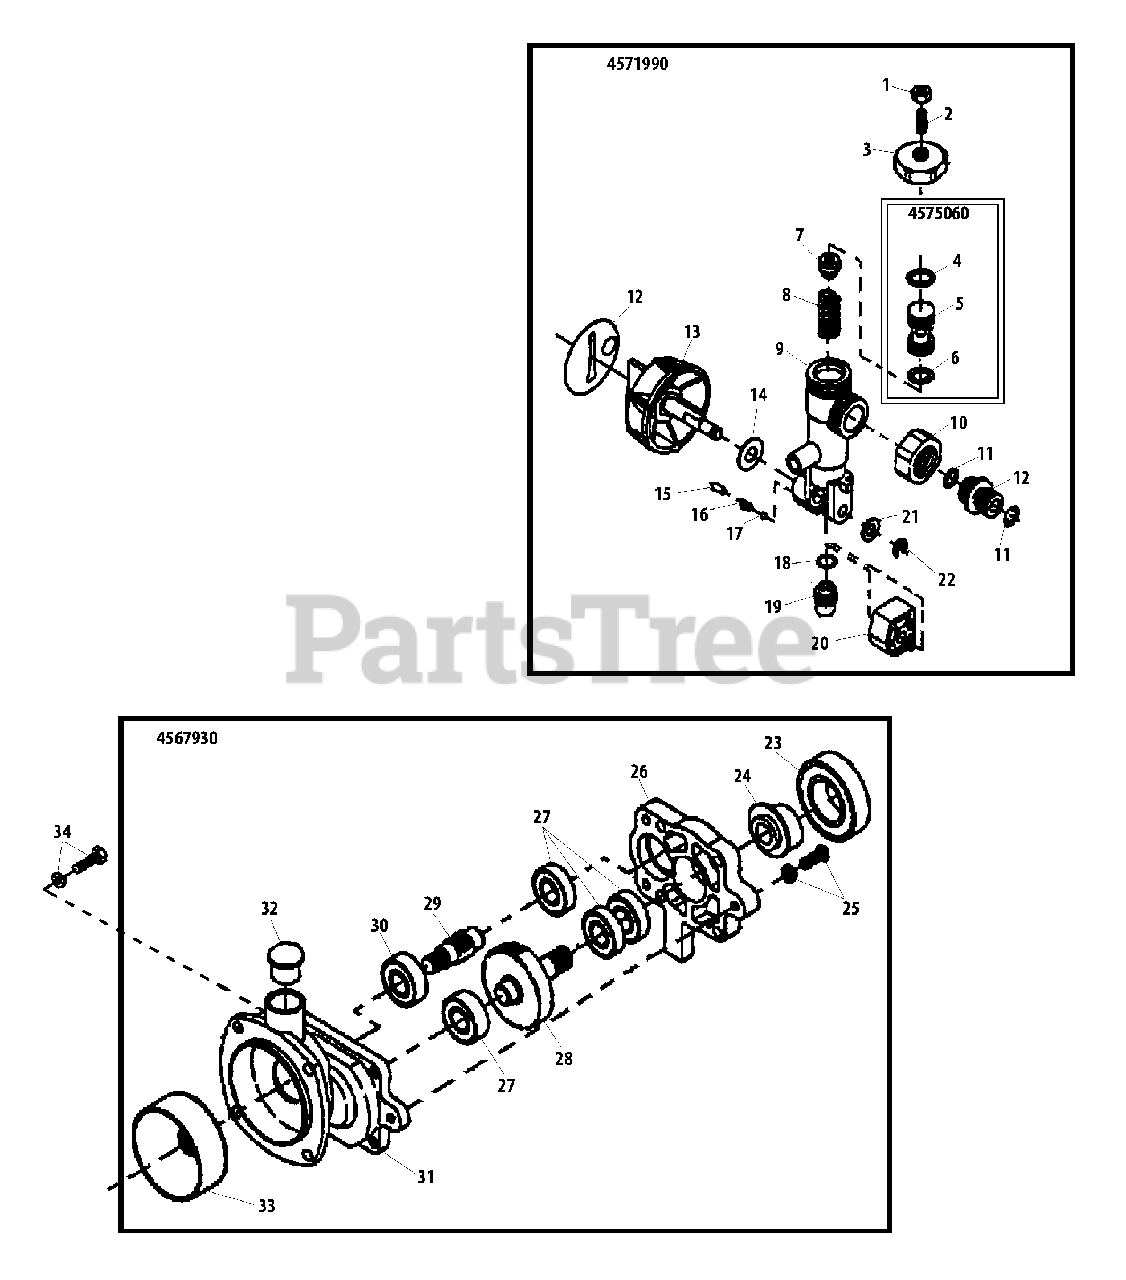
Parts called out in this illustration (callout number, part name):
3	NUT
4	O-RING
5	SEAT, VALVE
6	O-RING
7	VALVE
8	SPRING, VALVE
9	BODY, VALVE
10	LOCKNUT
11	O-RING
12	SEAL, VALVE
14	LOCKNUT
15	SPACER
16	SPRING
18	O-RING
21	WASHER
22	RING, RETAINING
23	BEARING, BALL
24	LOCKNUT
25	SCREW
26	BEARING HOUSING
27	BEARING, BALL
28	CRANKGEAR
29	GEAR - DRIVE
30	BEARING, BALL
31	CRANKCASE
32	CAP
33	DRUM, CLUTCH
4567930	GEAR CASE ASSY
4571990	VALVE ASSY
4575060	VALVE SET
